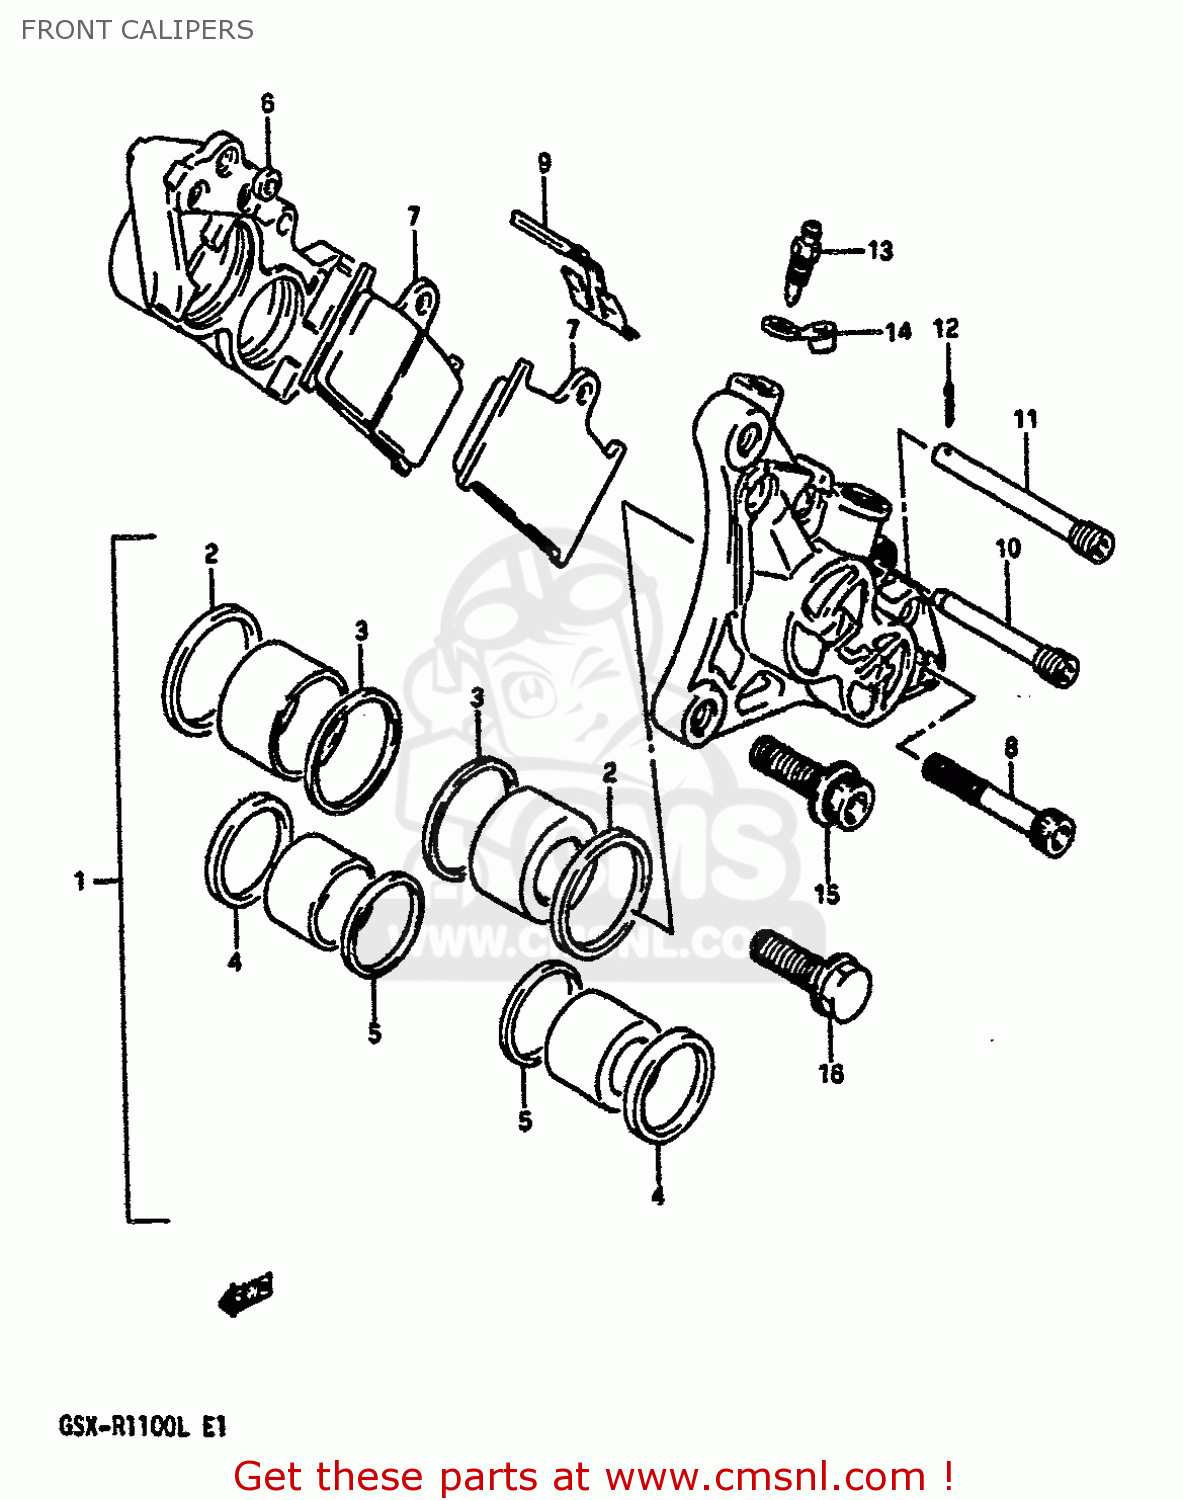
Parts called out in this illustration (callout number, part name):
1	PISTON SET
2	SEAL,PISTON
3	BOOT,PISTON
4	SEAL,PISTON
5	SEAL
6	SEAL
7	PAD
8	BOLT
9	SPRING
10	PIN,HOLDER
11	PIN,HANGER
12	COTTER PIN
13	BLEEDER
14	CAP,BLEEDER
15	BOLT
16	BOLT 10X30
